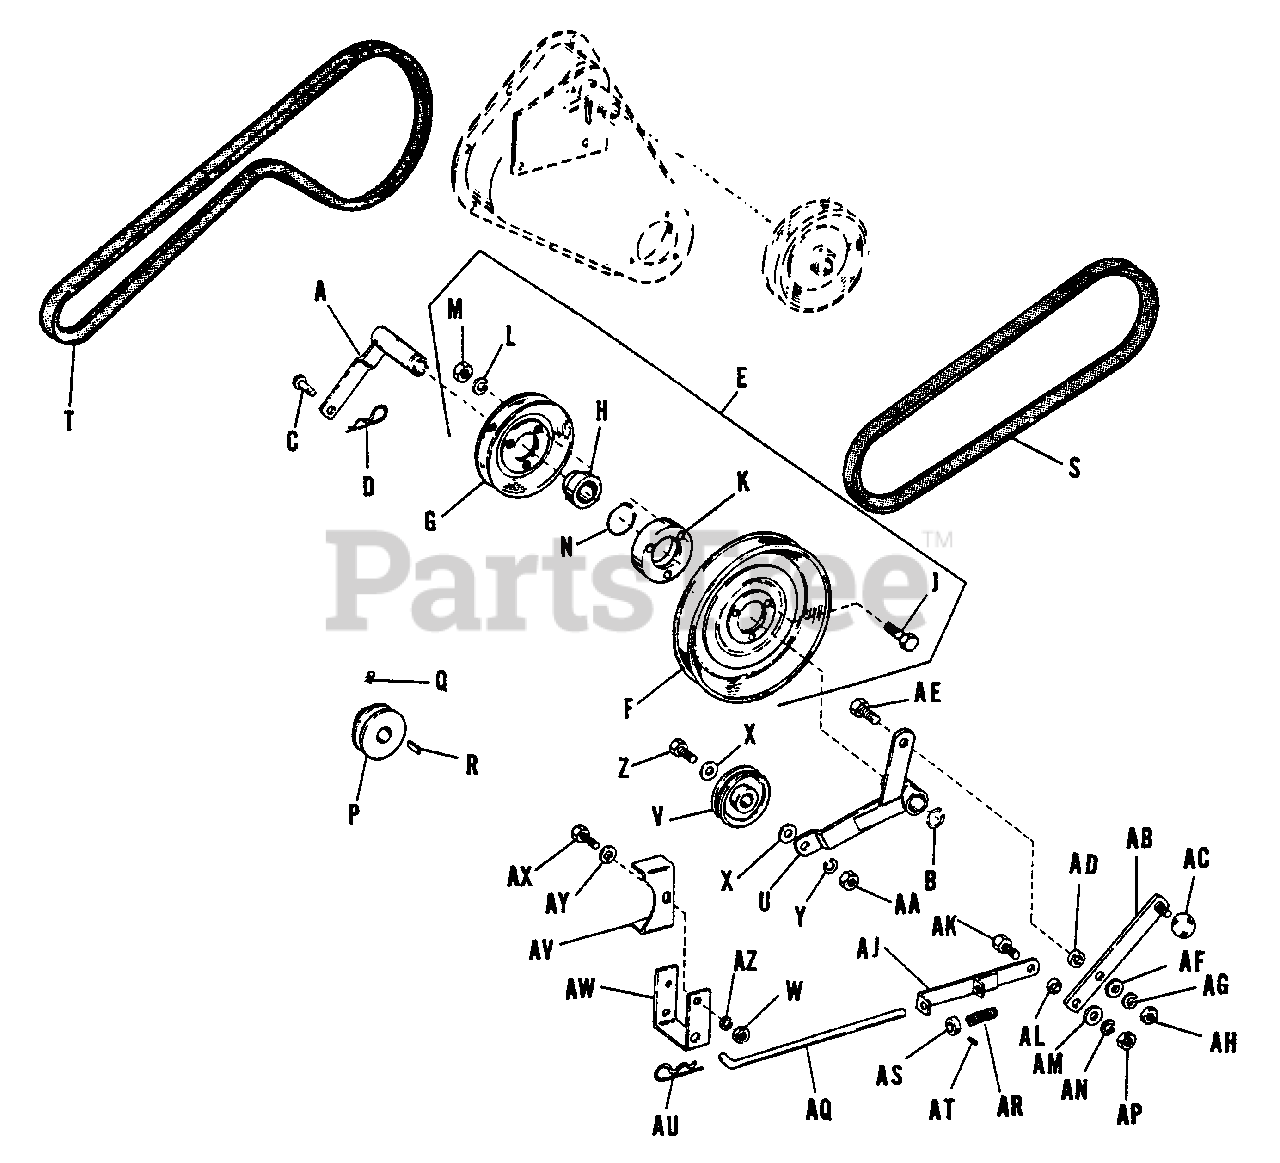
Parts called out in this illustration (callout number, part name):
A	Sleeve Assembly, Pulley
B	Ring, Snap
D	Clip, Spring
E	Pulley Assembly
F	Pulley, 10"
G	Pulley, 5 1/2"
J	Capscrew, Hex., 5/16"-18 NC x 1 3/4" lg.
L	Washer, Lock, 5/16"
M	Nut, Hex, Full, 5/16"-18 NC
N	Ring, Snap
P	Pulley, Tiller Drive
Q	Screw, Set, Cup Point, Socket Head, 5/16"-18 NC x 5/16" lg.
U	Lever Assembly, Idler
V	Pulley, Idler
W	Nut, Hex, Full, 3/8"-16 NC
X	Washer, Plain, 5/16"
Y	Washer, Lock, 3/8"
Z	Capscrew, Hex, 3/8"-16 NC x 1 1/4" lg.
AA	Nut, Hex, Full, 3/8"-16 NC
AB	Lever Assembly, Clutch
AE	Capscrew, Hex, 3/8"-16 NC x 1" lg.
AF	Washer, Plain, 3/8"
AG	Washer, Lock, 3/8"
AH	Nut, Hex, Full, 3/8"-16 NC
AJ	Guide Assembly
AK	Capscrew, Hex, 3/8"-16 NC x 7/8" lg.
AM	Washer, Plain, 3/8"
AN	Washer, Lock, 3/8"
AP	Nut, Hex, Full, 3/8"-16 NC
AS	Collar, Set
AT	Screw, Set, Square Head, Cup Point, 1/4"-20 NC x 3/8" lg.
AU	Clip, Spring
AV	Release, Belt
AW	Bracket, Belt Release
AX	Capscrew, Hex, 3/8"-16 NC x 7/8" lg.
AY	Washer, Plain, 3/8"
AZ	Washer, Lock, 3/8"
